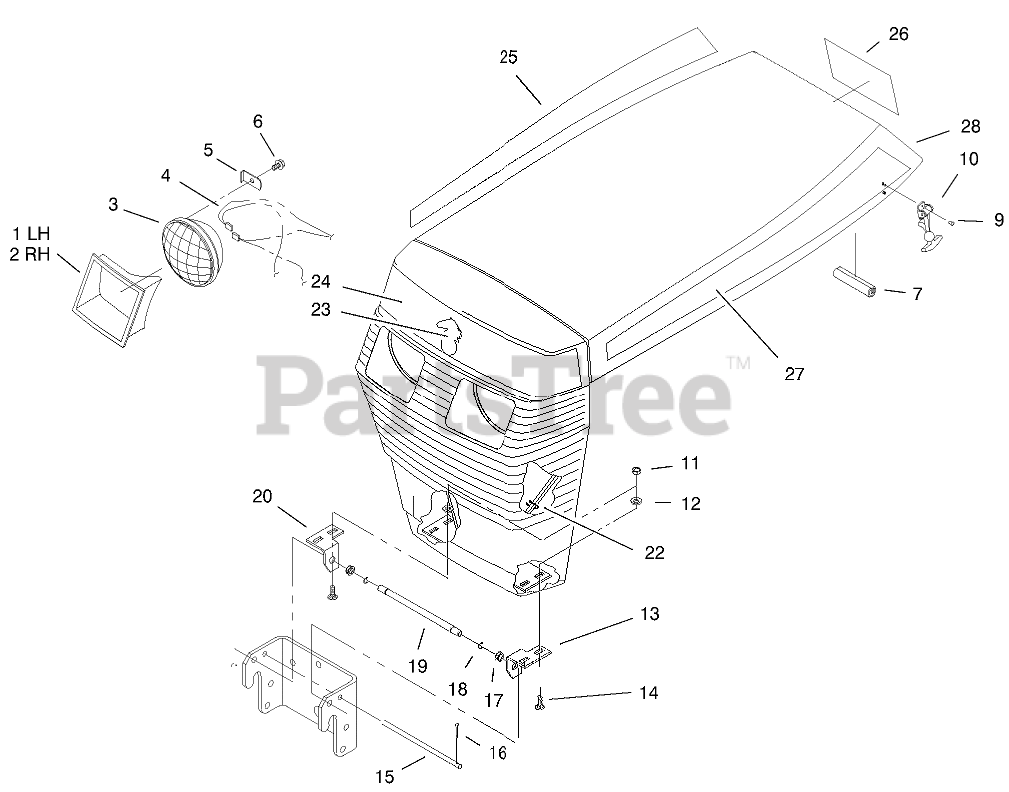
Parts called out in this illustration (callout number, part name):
1	BEZEL-HEADLIGHT, LH
2	BEZEL-HEADLIGHT, RH
3	HEADLAMP
4	HARNESS-HEADLIGHT
5	LOCK-HEADLIGHT
6	SCREW-HWH
7	EDGING-CONSOLE
9	RIVET-POP
10	HANDLE ASM
11	NUT-LOCK, NI
12	WASHER-FLAT
13	BRACKET-GRILL, LH
14	SCREW-CARR
15	ROD-HOOD STOP
16	PIN-COTTER
17	BUSHING-NYLINER
18	RING-RETAINING
19	ROD-GRILL PIVOT
20	BRACKET-GRILL, R H
22	TIE-CABLE
23	LOGO - HORSEHEAD
24	DECAL-FRONT HOOD, TOP
25	DECAL - RH HOOD TOP
26	DECAL-DANGER, HOOD
27	DECAL - LH HOOD TOP
28	Hood
